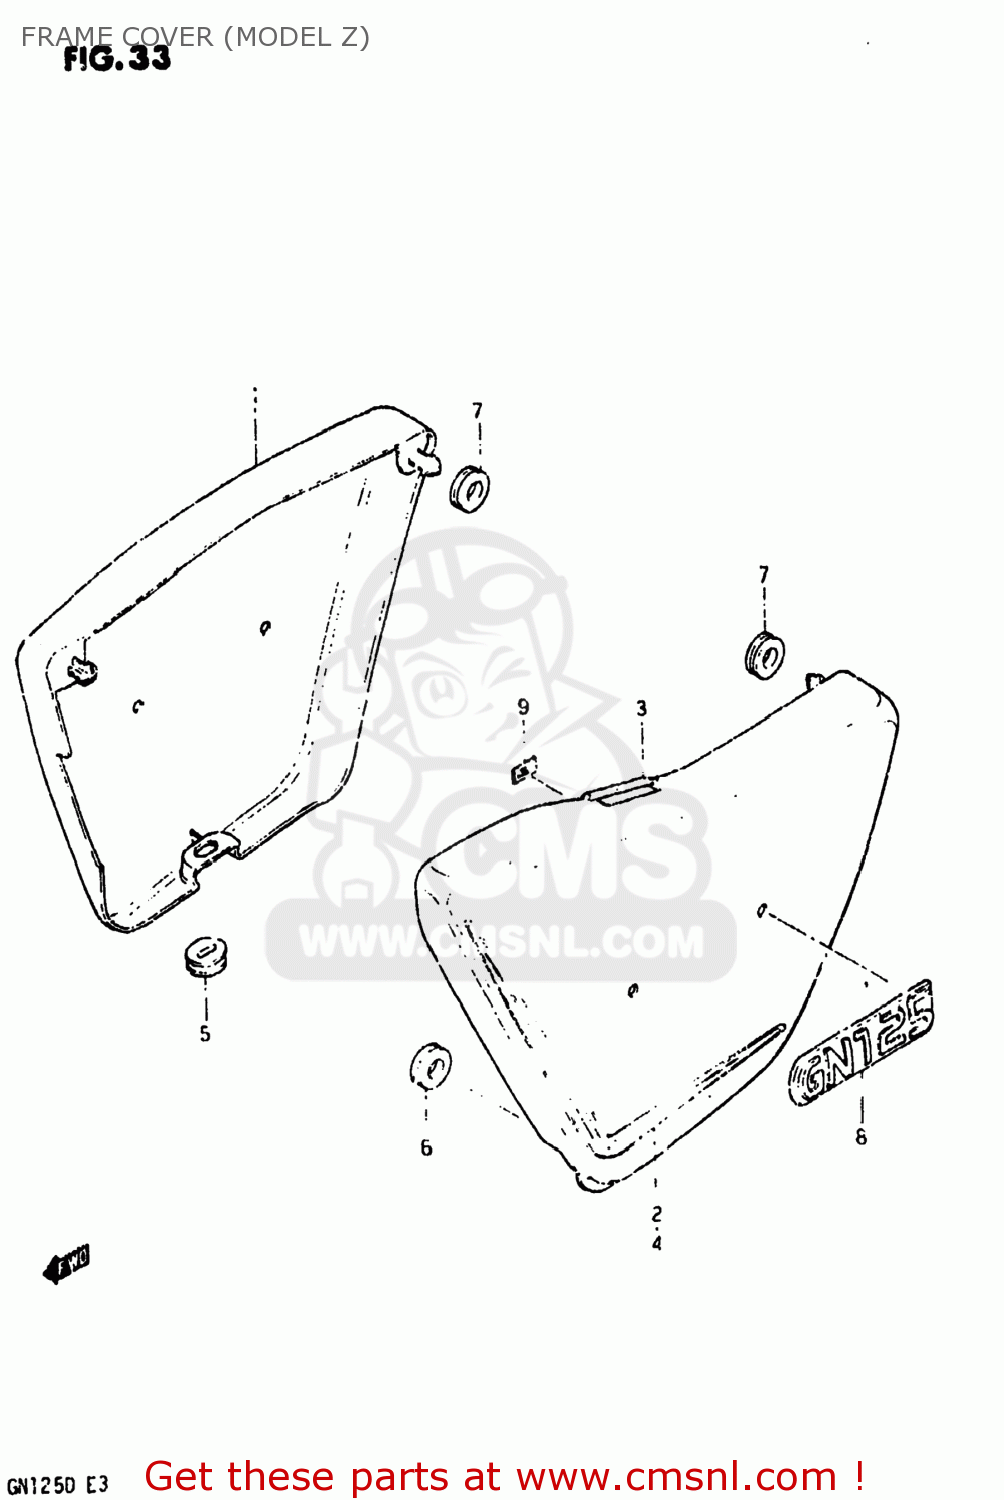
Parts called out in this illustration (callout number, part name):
1	COVER,FRAME,RIGHT
2	TAPE,FRAME COVER
3	COVER,FRAME,LEFT
4	TAPE,FRAME COVER
5	CUSHION
6	CUSHION
7	CUSHION
8	EMBLEM,FRAME COVER
9	NUT
